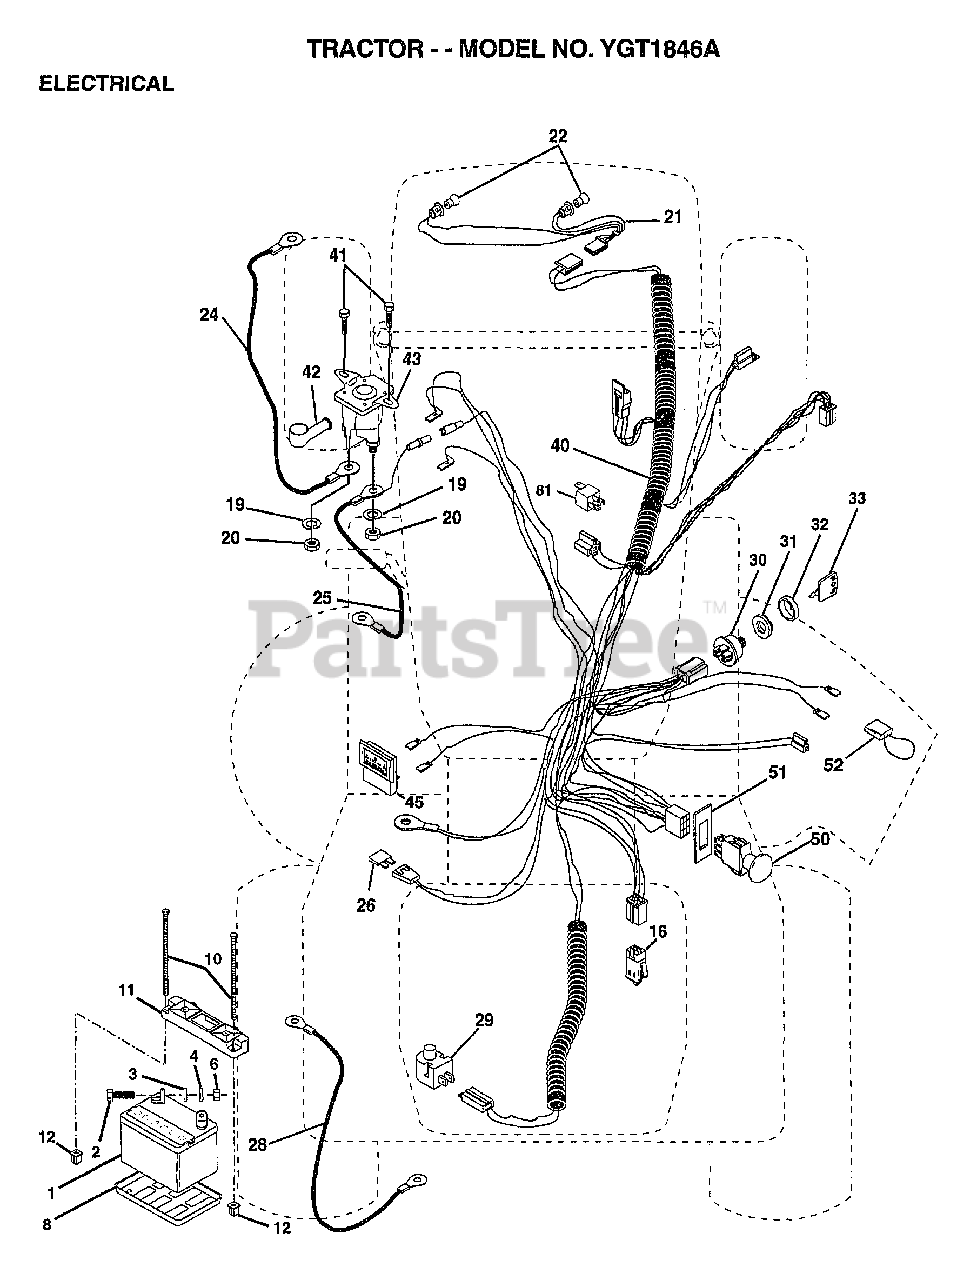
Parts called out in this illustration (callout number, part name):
2	BOLT LT
3	LOCKWASHER
4	WASHER
8	"TRAY T, BATTERY"
11	HOLDDOWN BATTERY
16	SWITCH INTERLOCK
20	NUT
21	"HARNESS,LIGHT SOC"
22	HEADLAMP BULB
24	CABLE.BATY.22.RED
25	CABLE.BATRY.4GA.
26	FUSE HYT
28	"CABLE BATTERY,GRD"
29	SWITCH.PLUNGER
30	SWITCH IGN 4POS
31	NUT IGNITION
32	COVER KEY SWITCH
33	KEY
40	HARNESS.IGN.
41	SCREW
45	AMMETER
50	PTO SWITCH.BLK
51	RING RETAIN PTO
52	PROTECTION LOOP
81	RELAY ASSY T
